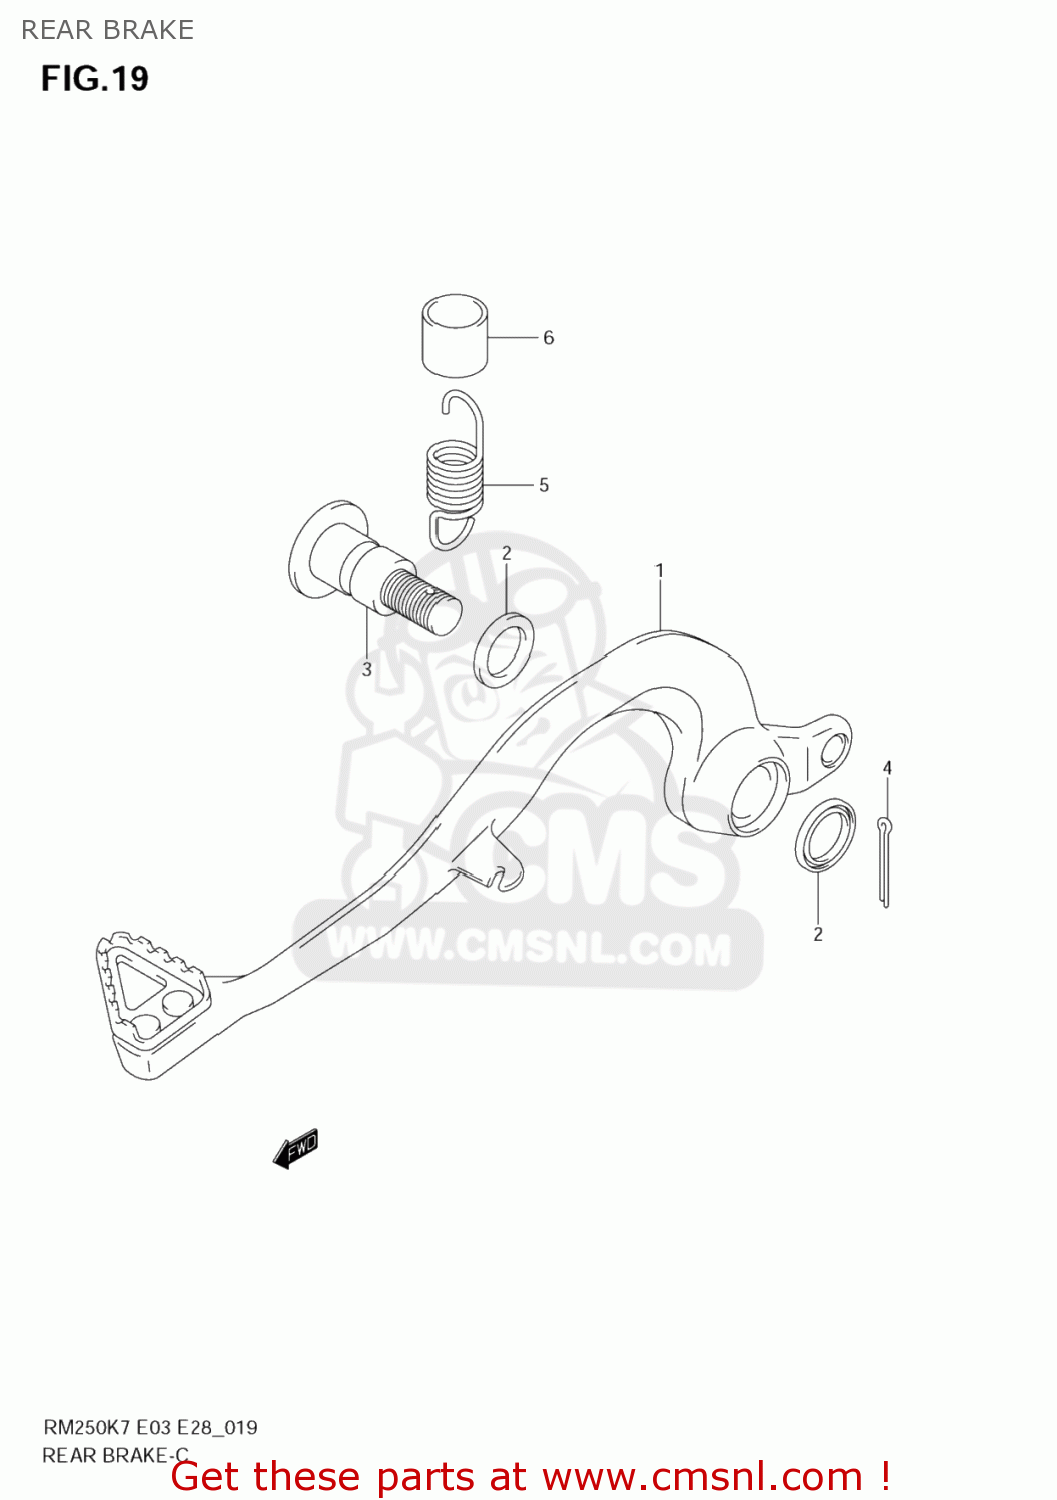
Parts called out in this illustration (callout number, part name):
1	PEDAL ASSY,BRAKE
2	SEAL,OIL(15X21X3)
3	SHAFT,BRAKE PEDAL
4	PIN
5	SPRING
6	PROTECTOR,SPRING
